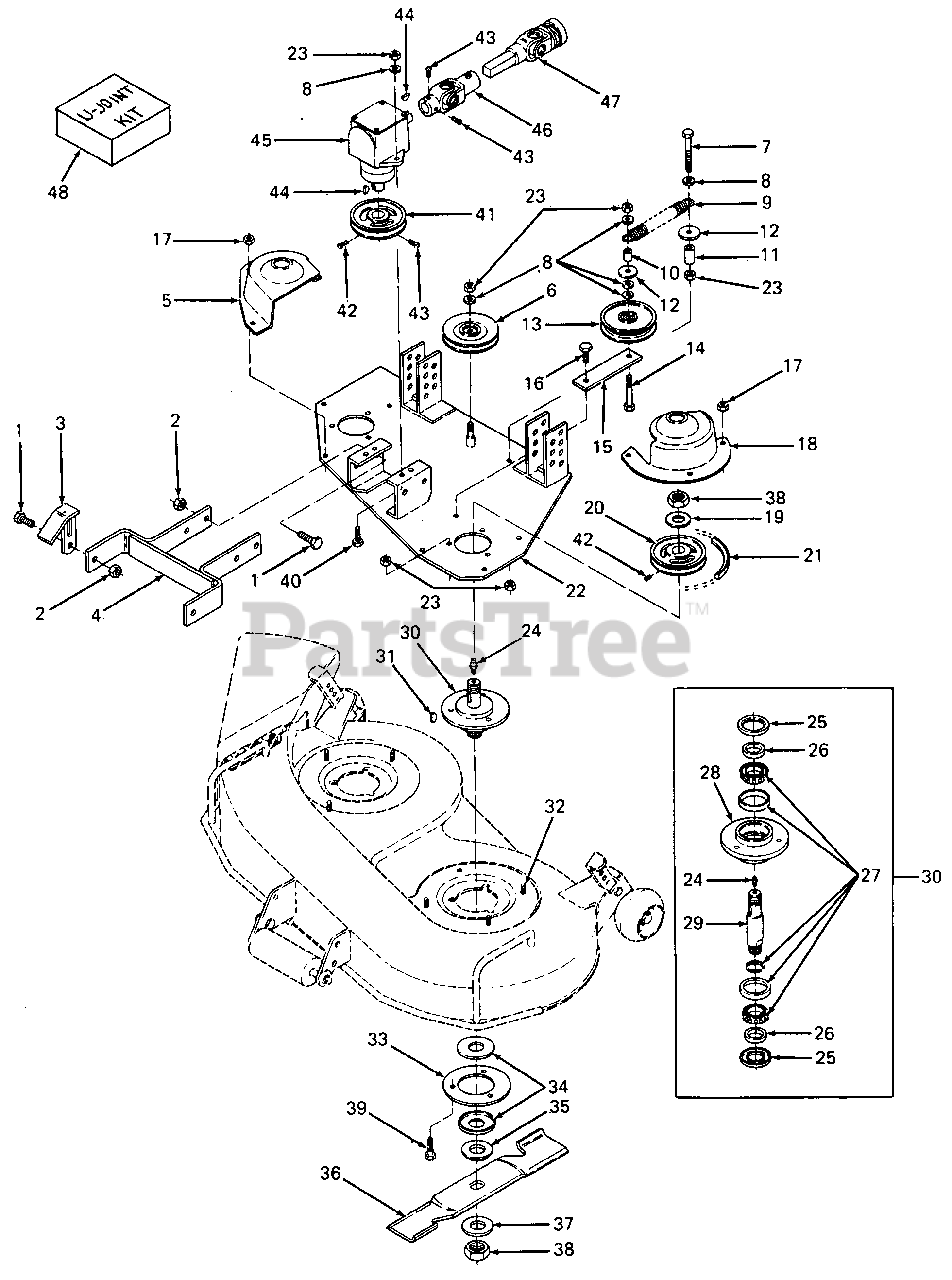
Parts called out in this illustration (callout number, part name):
1	Screw, Hex Cap, 1/2-13 X 1.0 Lg GR5
2	Nut, Hex Center Lock, 1/2-13
3	Hanger Assy, Deck w/Graphic
5	Cover, Belt, RH
6	Pulley, Idler
7	Screw, Hex Cap, 3/8-16 X 2.25 Lg
8	Washer, Flat, .406 X .734 X .063
9	Spring, Idler Extension
13	Pulley, Idler
14	Screw, Hex Cap, 3/8-16 X 2-3/4 Lg
15	Idler, Mower
16	Screw, Shoulder
17	Nut, Hex Center Lock, 5/16-18
18	Cover, Belt, LH
19	Washer, Flat
20	Pulley, Spindle
21	Belt, Mower
22	Plate, Deck
23	Nut, Hex Center Lock, 3/8-16
24	Fitting, Grease
27	Bearing Assy, Tapered
28	Housing, Spindle
29	Shaft, Spindle
30	Spindle Assy
31	Key, Hi-Pro, 1/4 X 1
33	Ring, Spindle
34	Shield, Bearing
35	Ring, Blade Support
36	Blade, Mower, 19.38 Lg
37	Washer, Flat
39	Screw, Hex Cap, 3/8-16 X 1-1/2 Lg GR5
40	Screw, Hex Cap, 3/8-16 X 1-1/4 Lg
41	Pulley, Deck Gearbox
42	Setscrew, 5/16-18 x 5/8 Sq Hd Cup
43	Setscrew, 5/16-18 x .50 Sq Hd Cup
44	Key, Hi-Pro, 3/16 X .75 HDN
45	Gearbox, Right Angle
46	Driveshaft, Female
47	Driveshaft, Quick Disconnect
48	Kit, U-Joint Service
